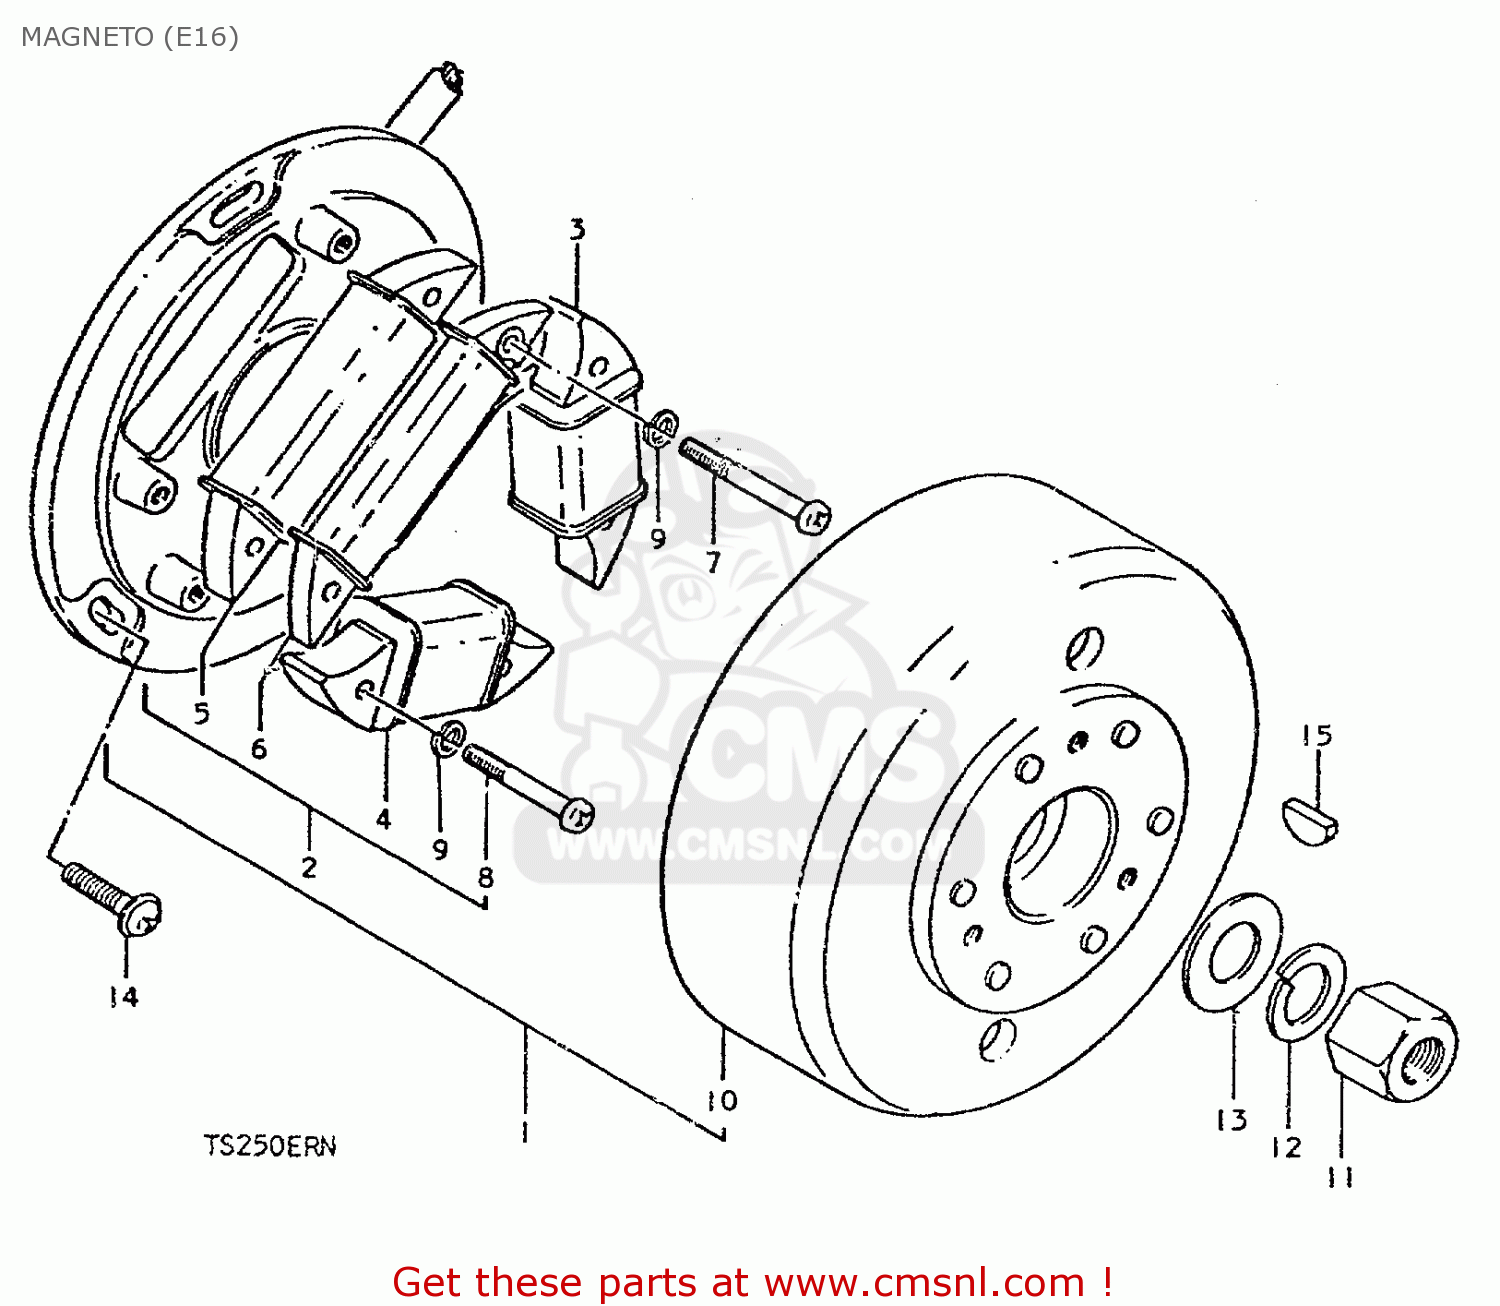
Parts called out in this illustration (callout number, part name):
1	MAGNETO ASSY
2	STATOR ASSY
3	COIL, LIGHTING
4	COIL,LIGHTING
5	COIL
6	COIL,PULSER
7	SCREW 5X35
8	SCREW 5X20
9	LOCK WASHER
10	ROTOR,FLYWHEEL
11	NUT
12	LOCK WASHER
13	WASHER(14X27X3)
14	SCREW(5X14)
15	KEY 4MM
